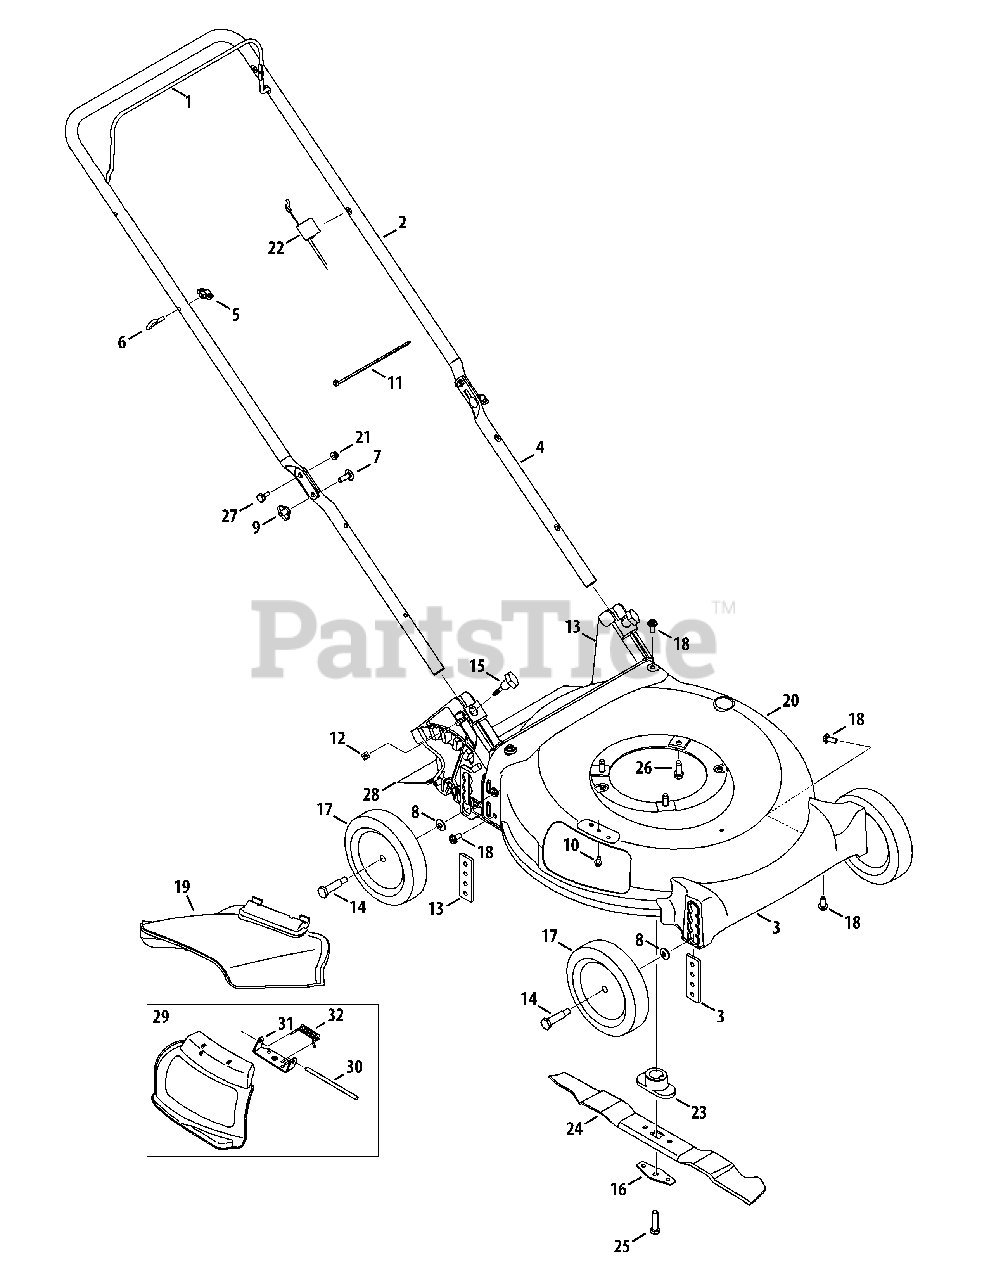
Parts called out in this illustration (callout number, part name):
1	Blade Control
2	Upper Handle
3	Front Cover Assembly
4	Lower Handle
5	Wing Nut
6	Rope Guide
7	Carriage Screw ,5/16-18
8	Washer, .401 x .870 x .060
9	Wing Knob
10	Screw, 1/4-20 x .500
11	Cable Tie
12	Nut, Sq., 1/4-20
13	Rear Baffle, HD
14	Shoulder Screw
15	Wing Nut
16	Blade Bell Support
17	Wheel, 7" Star-Dia., Oys. Gray
18	Screw, 5/16-14 x .750
19	Side Chute
20	Deck , 21"
21	Nut, Flange Lock, 1/4-20
22	Control Cable
23	Blade Adapter
24	Mulching Blade
25	Screw , 3/8-24 x 1.50
26	TT Sems Screw, 3/8-16 x 1.0
27	Sldr. Screw, .375 x .126 x 1/4-20
28	Trail shield
29	Hinged Mulch Plug Assembly
30	Hinge Pin
31	Chute Deflector Bracket
32	Torsion Spring
